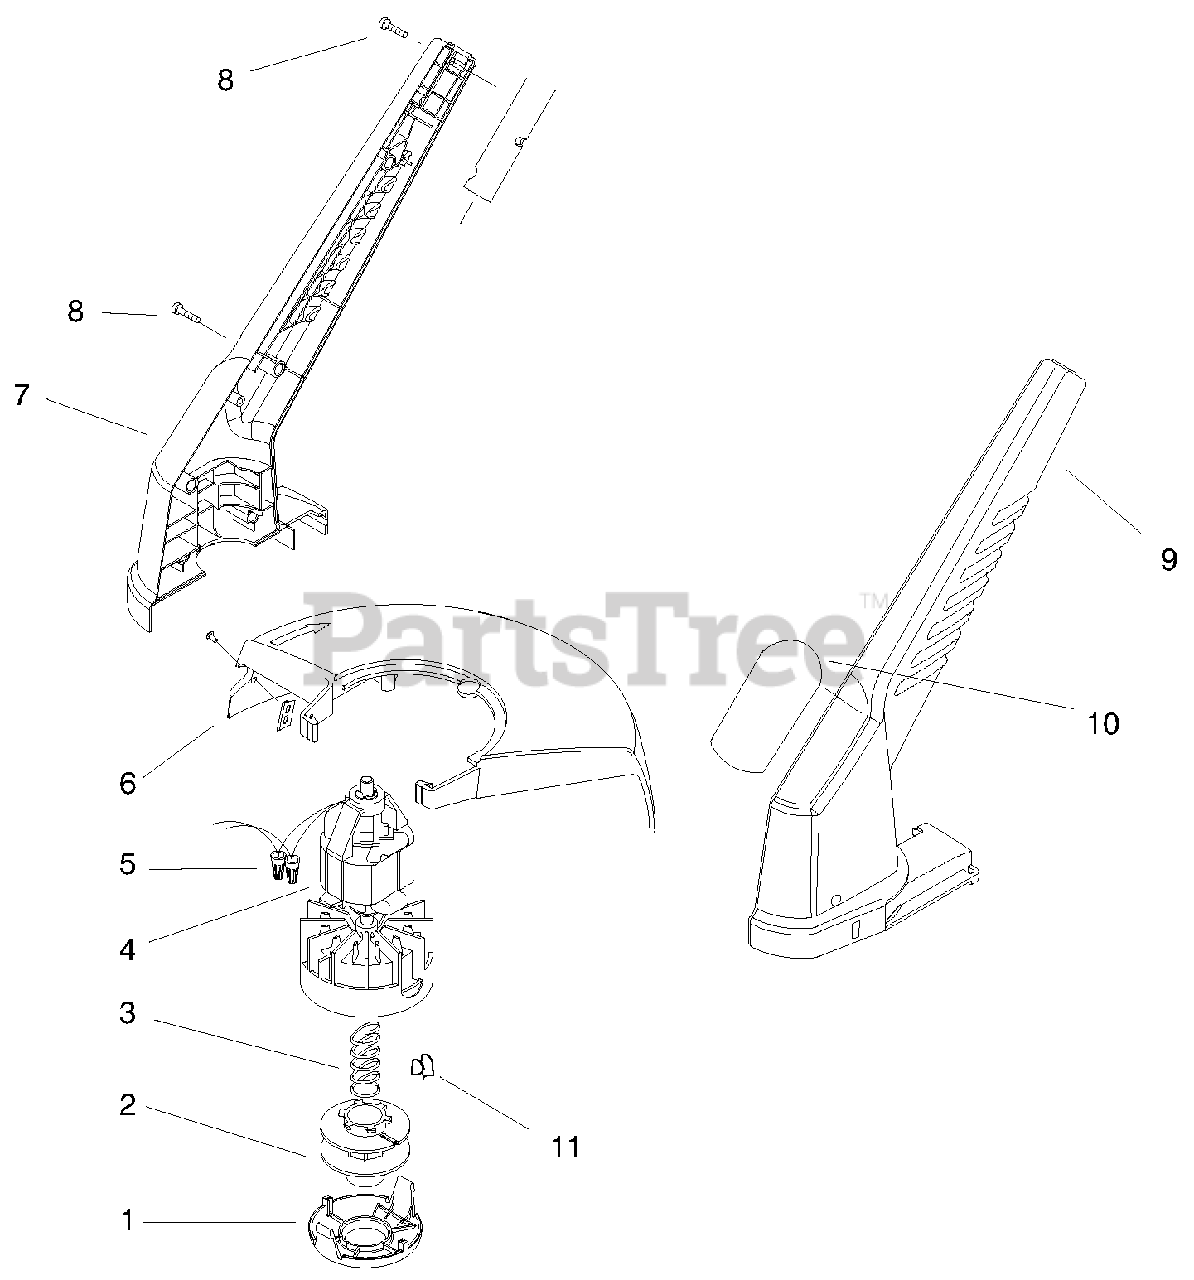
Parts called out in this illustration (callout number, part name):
2	SPOOL-LARGE
3	SPRING - COMPRESSION
4	Motor Assembly (Includes Ref. #11)
5	CONNECTOR-WIRE NUT
6	SHIELD ASSEMBLY-11"
7	HOUSING-RH
8	SCREW-PPH
9	HOUSING-LH
10	DECAL, 11" TRIMMER/EDGER
